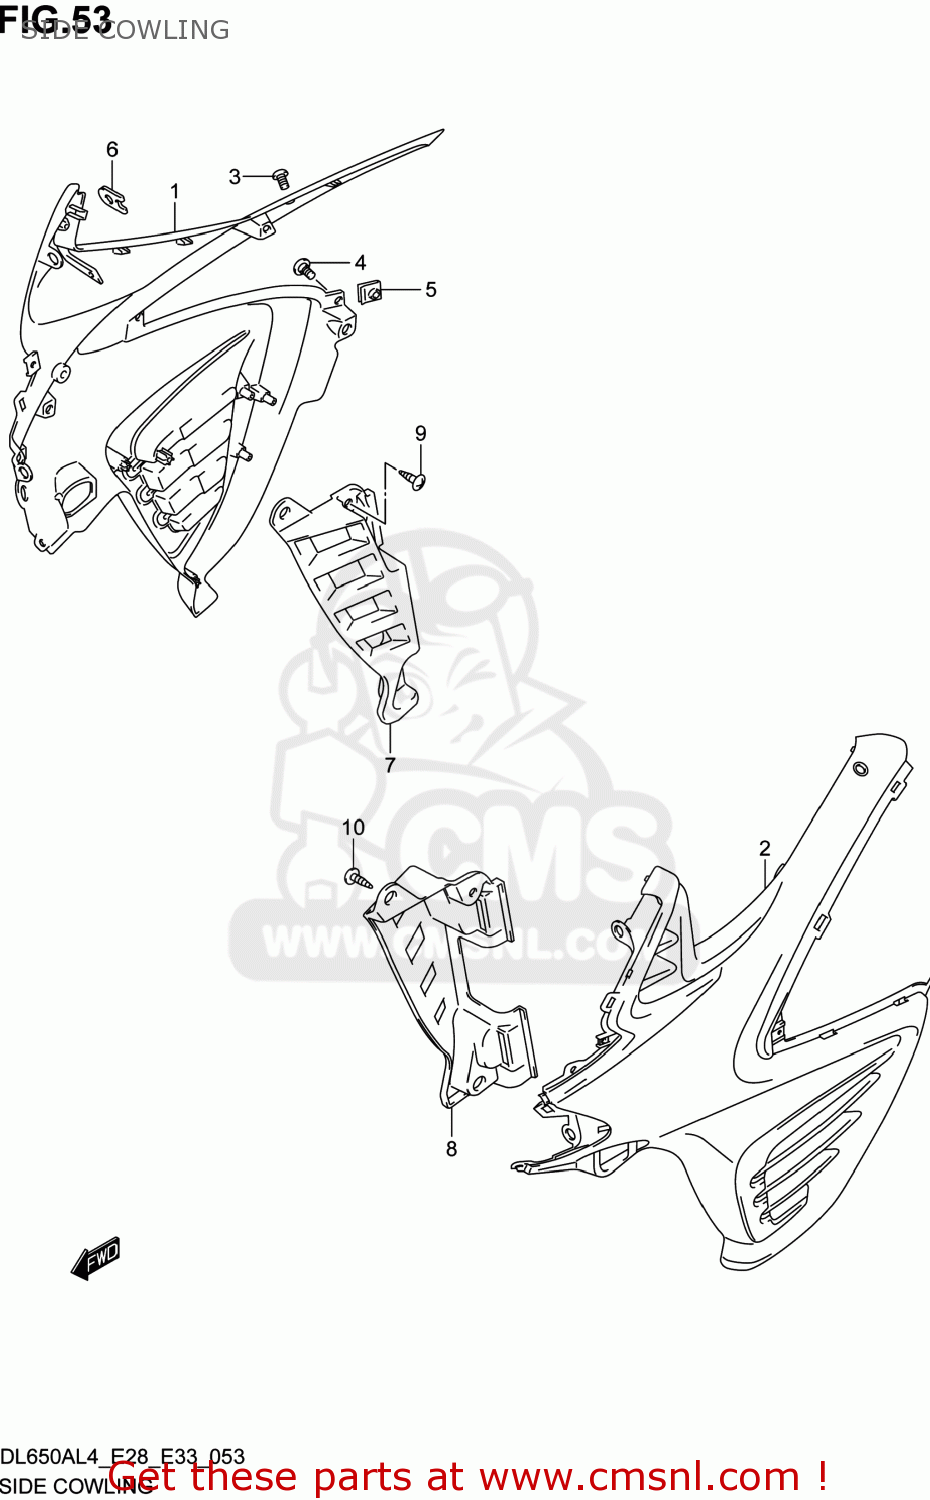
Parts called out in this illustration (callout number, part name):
1	COWLING,SIDE,R
2	COWLING,SIDE,L
3	SCREW(6X10)
4	SCREW(6X12)
5	NUT
6	NUT
7	COVER,COWLING INNER,R
8	COVER,COWLING INNER,L
9	SCREW
10	SCREW
